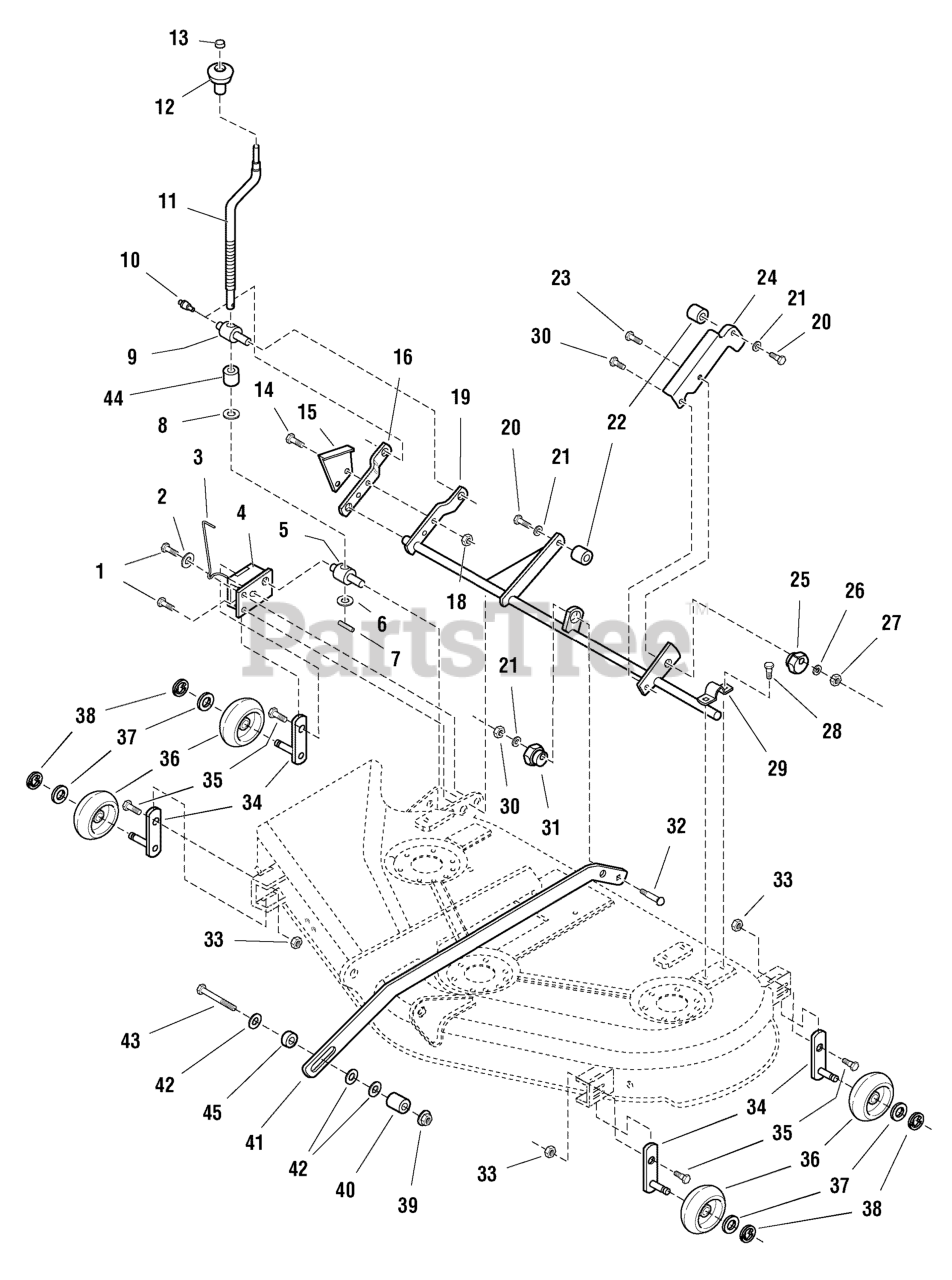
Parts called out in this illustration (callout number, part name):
1	CAPSCREW, Hex Washer Head Taptite, 5/16-18 x 1-1/4
2	WASHER, 5/16
3	ROD, Indicator Height of Cut
4	PLATE & BRACKET ASSEMBLY, Gauge Wheel
5	TRUNNION, 1-1/4
6	WASHER, Detent
7	PIN, Spring
8	WASHER, 9/16
9	TRUNNION, 1-1/4
10	FITTING, Lube
11	CRANK, Height Adjustment
12	KNOB, Spinner, Soft
13	NUT, Push
14	CAPSCREW, Hex Head, 5/16-18 x 1 1/4
15	BRACKET, Height of Cut
16	ARM, Rear
18	NUT, Hex Whiz Lock, 5/16-18
19	ARM ASSEMBLY, Roller Bar 50"
19	ARM ASSEMBLY, Roller Bar 44"
20	CAPSCREW, Hex Head, 3/8-16 x 1, G5
21	LOCKWASHER, Spring, 3/8
22	SPACER, Support
23	CARRIAGE BOLT, 5/16-18 x 1-1/4, G5
24	ARM, Rear Adjustable
25	CAM, Eccentric, Hex
26	WASHER, 5/16
27	NUT, Hex Flange Collar Lock , 5/16-18
28	CAPSCREW, Hex Washer Head Taptite, 5/16-18 x 3/4
29	STRAP
30	NUT, Hex 3/8-16
31	NUT, Hex Adjusting, 11/16
32	PIN, Round Head, Drilled, 3/8 x 2
33	NUT, Hex Flange Toplock 1/4-20
34	SHAFT & BAR ASSEMBLY, Roller Fixed Arm
35	CAPSCREW, Hex Head, 1/4-20 x 3/4, G5
36	WHEEL, Roller
37	WASHER, 1/2
38	E-RING, Retaining Extension
39	NUT, Hex Two-Way Lock Flange, 3/8-16
41	ARM, Pitch 44"
41	ARM, Pitch 50"
42	WASHER, 3/8
43	CAPSCREW, 3/8-16 x 2
44	SPACER, .66 X 7/8 X 1 1/4
